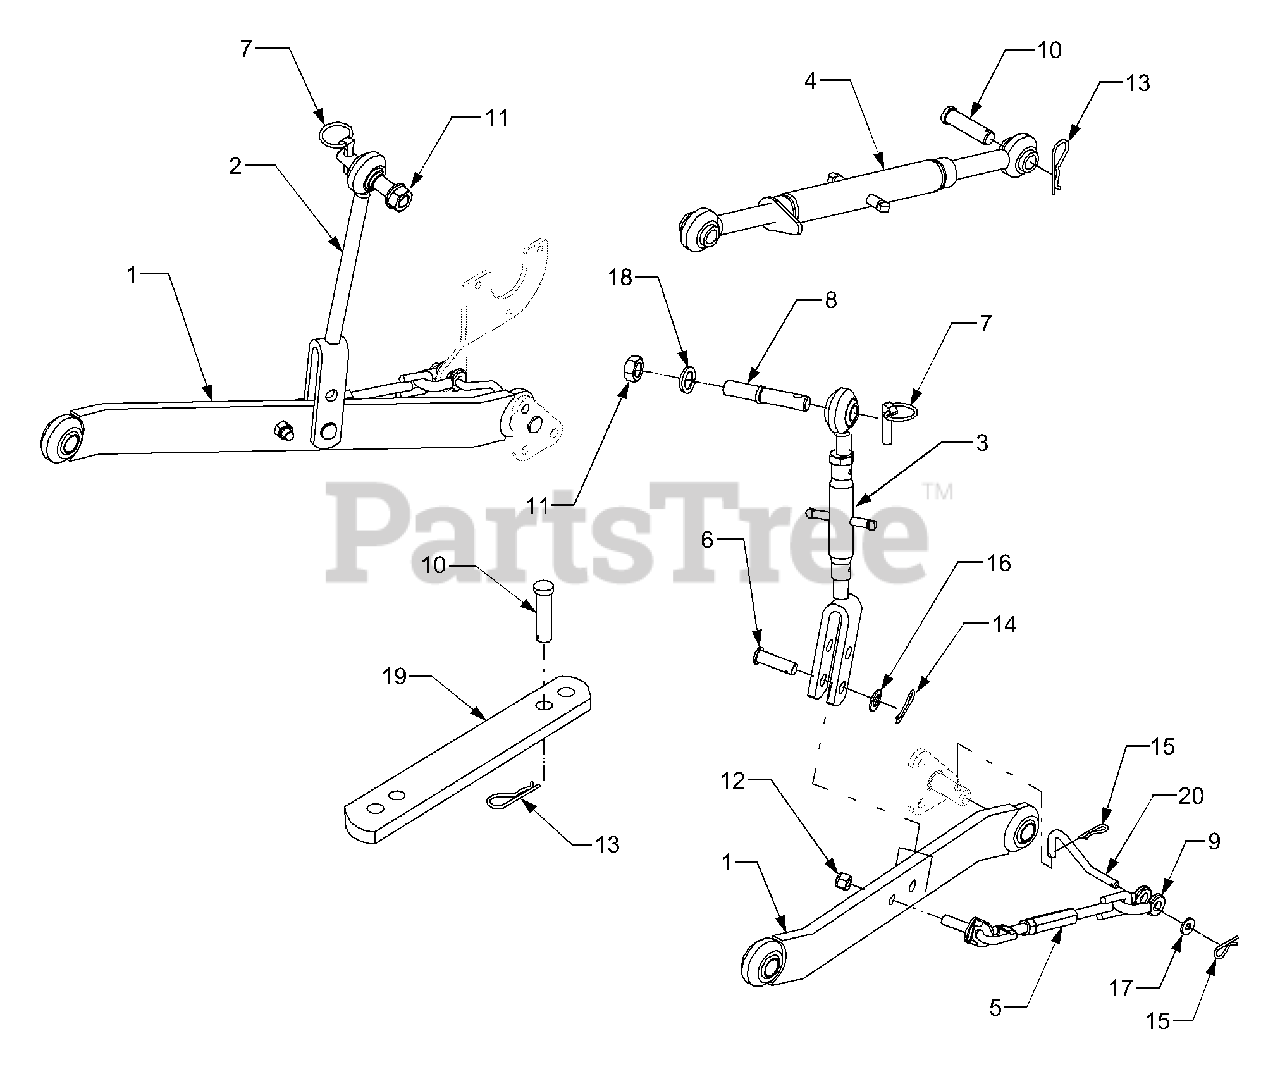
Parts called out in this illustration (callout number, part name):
3	Link, Lift - Adjustable
4	Link, Upper Center
5	Chain Assembly, Check
6	Pin, Clevis, .624 Dia
7	Pin, Klik, 1.75 Lg.
8	Pin, Upper Lift Arm
9	'U' Clevis, Check Chain
10	Pin, Clevis, .75 x 2.75
11	Nut, Hex, 3/4-10 GR5
12	Nut, Hex Insert Lock, 1/2-20
13	Pin, Internal Cotter, .148 x 3.0
14	Pin, Internal Cotter, .125 x 1.75
15	Pin, Internal Cotter
16	Washer, Flat, .635 x 1.12 x .09
17	Washer, Flat, .385 x .87 x .09
18	Washer, Lock, 3/4
